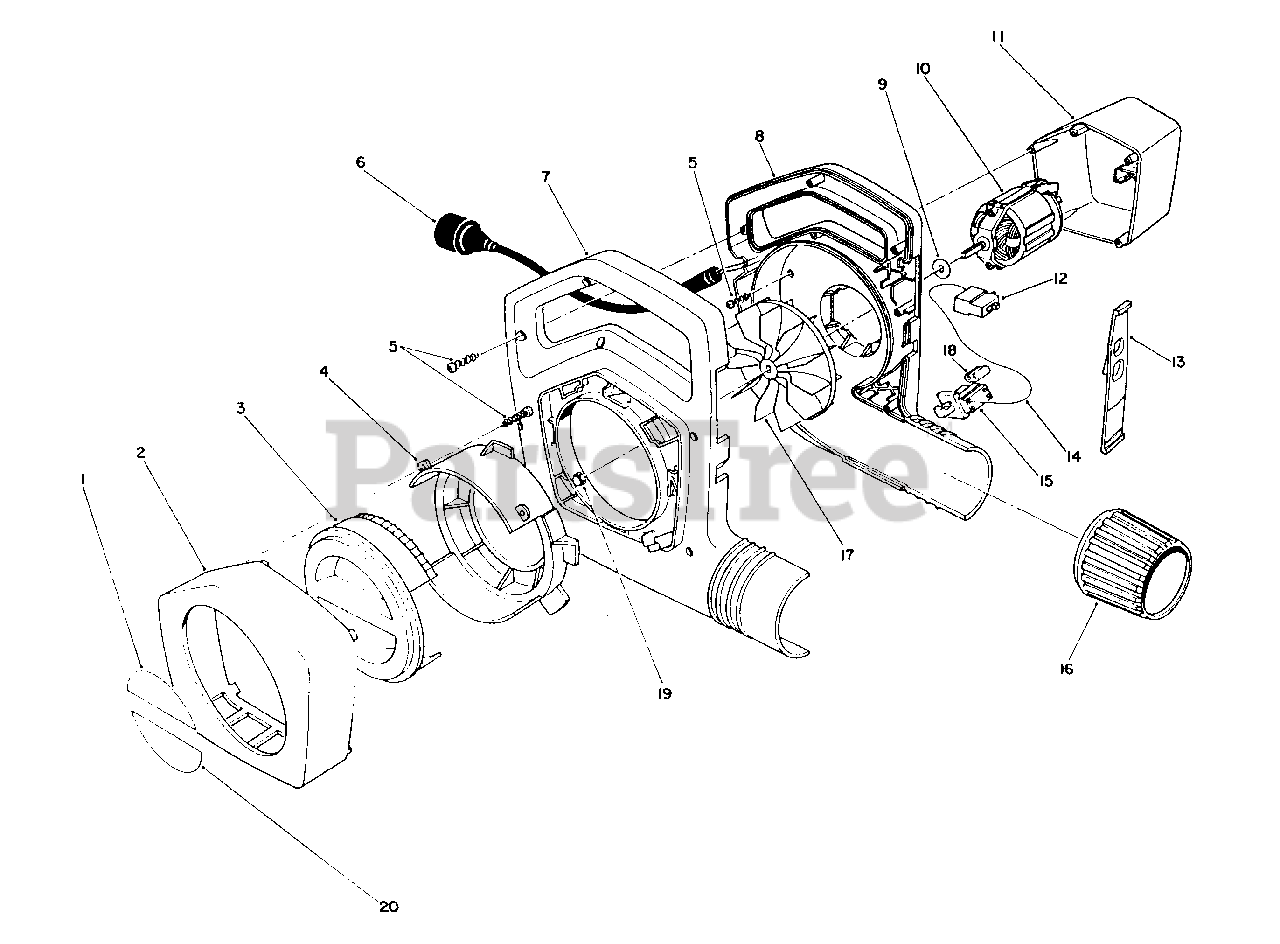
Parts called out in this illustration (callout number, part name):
1	Decal-Choke, Upper (Model No. 51535)
1	Decal-Choke, Upper (Model No. 51545)
2	Ring-Trim
3	Adjuster-Choke
4	Ring-Tab
5	Screw
6	Cord-Power Supply
7	Housing Assembly-R.H.
8	Housing-L.H.
9	Washer-Impeller
11	Cover-Motor
12	Switch-On/Off
13	Cam-Switch, On/Off
14	Wire-Internal
15	Switch-Interlock
16	Collar-Output
17	Impeller
18	Plug-Dust
20	Decal-Choke, Lower (Model No. 51535)
20	Decal-Choke, Lower (Model No. 51545)
